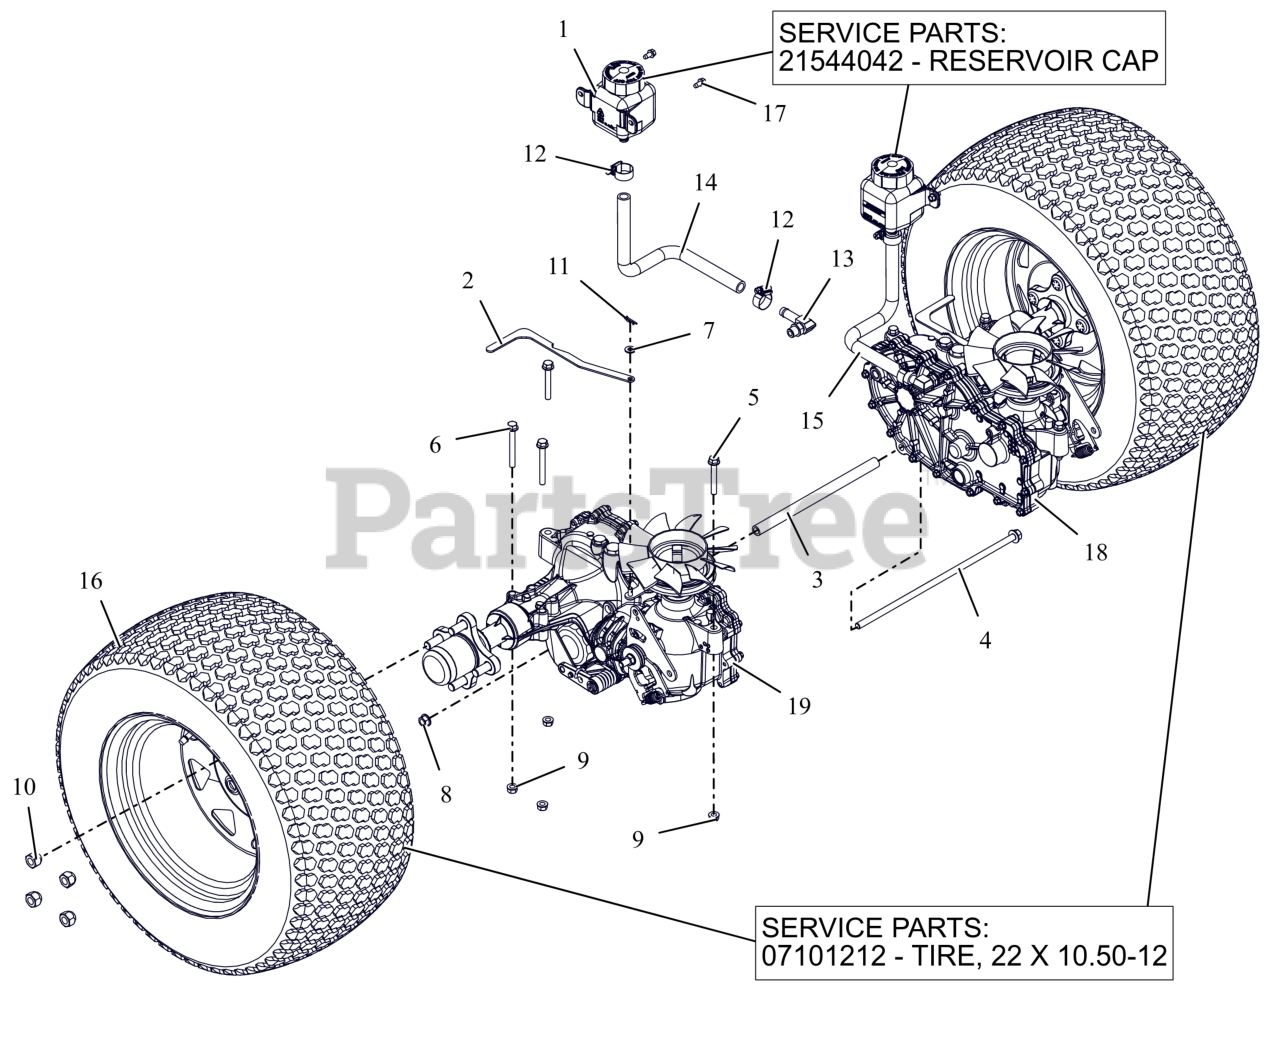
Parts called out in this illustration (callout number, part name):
1	TANK, EXPANSION
1	CAP, HYDRO RESERVOIR REPLAC.
2	BRKT, VALVE DUMP
3	SPCR,TRANS. .406IDX.63ODX9.95L
4	BLT,HEX-FLG .38-16X13 G5 ZCC
5	BLT,HEX-FLG .31-18X2.25 G5 ZCC
6	BLT,HEX-FLG .31-18X2.75 G5 ZCC
7	WSHR,FLT .281X.625X.065 ZCC
8	NUT-LK-TOP-FLG .38-16 ZC120
9	NUT,LK-CTR-FLG .31-18 GF ZCC
10	NUT, WHEEL .50-20 ZCC
11	PIN, HAIR #225 .072X1.09
12	CLAMP,.88 DIA. HOSE
13	FITTING, HYD (90 DEG)
14	HOSE, FORMED EXPANSION -HD RH
15	HOSE, FORMED EXPANSION -HD LH
16	ASM, WHL/TIRE 22X10.50-12 K500
16	TIRE, 22X10.50-12
16	VALVE STEM ASS'Y
16	TIRE TUBE 22,23,24/8.50/9.50/10.00/10.50/12.00-12 4 PLY TR13 STRAIGHT VALVE
17	SCR-TAP .25-20X.50 HWH ZCC
18	TRANSAXLE, ZT3100 - LH
19	TRANSAXLE, ZT3100 - RH
